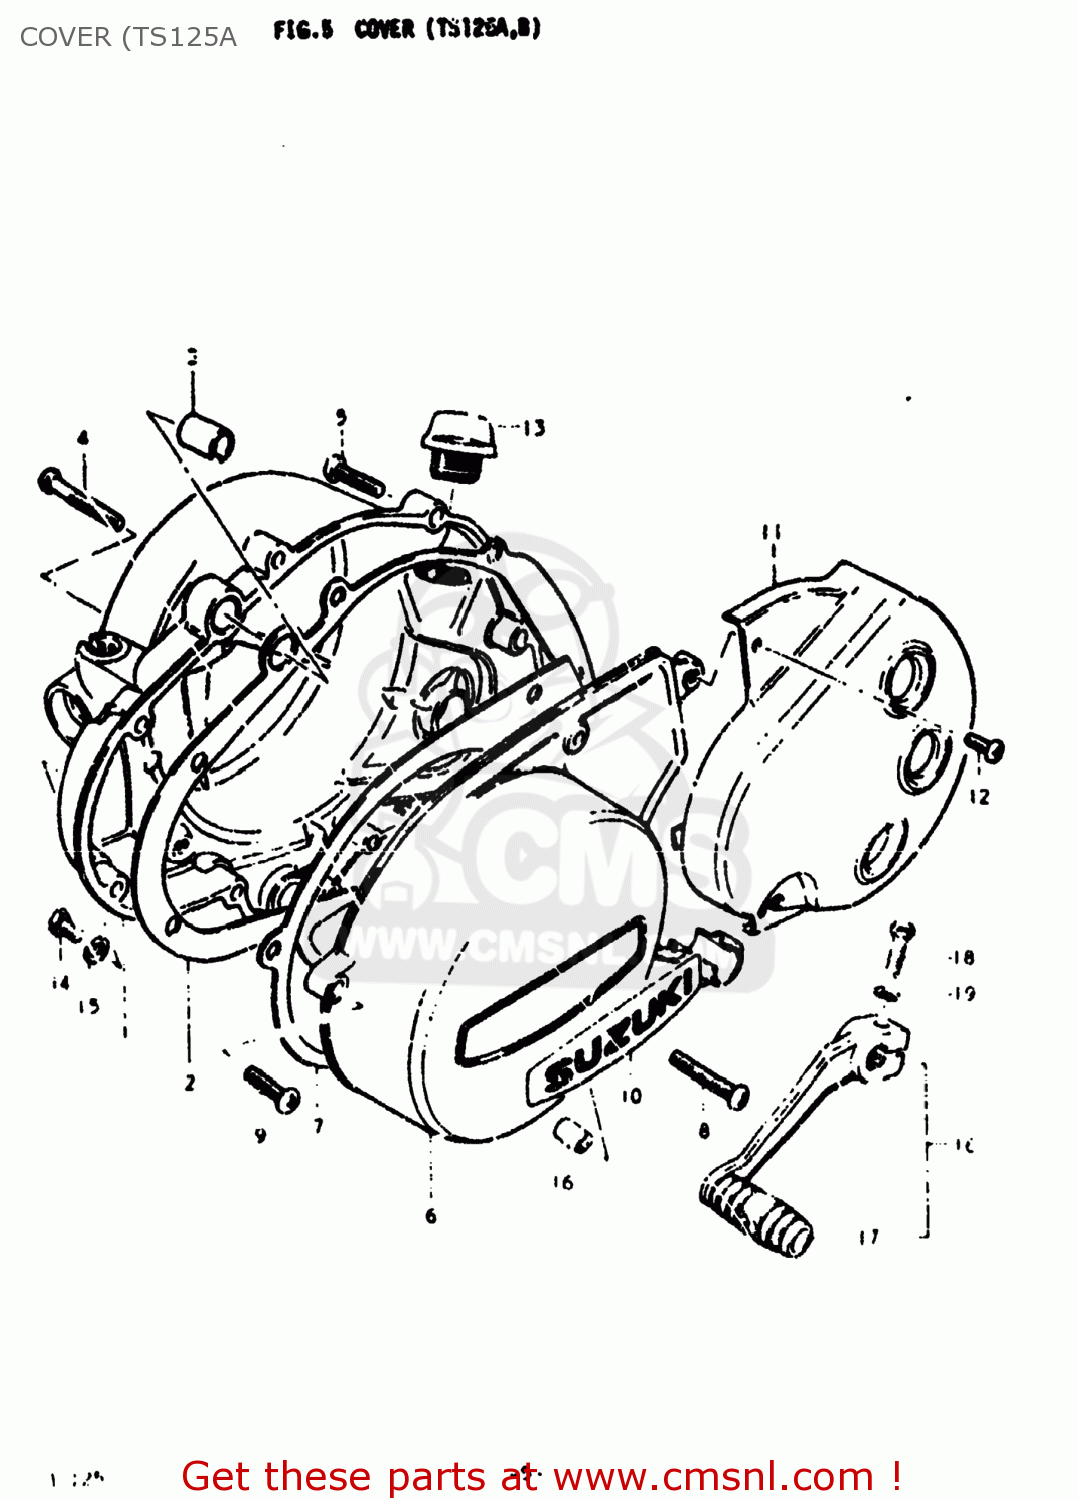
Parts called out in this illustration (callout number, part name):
1	CLUTCH COVER
2	GASKET,CLUTCH COVER (MCA)
3	PIN
4	SCREW (6X45)
5	SCREW
6	COVER
7	GASKET,CLUTCH COVER (NAS)
8	SCREW
9	SCREW
10	EMBLEM,MAGNETO COVER
11	COVER,ENGINE SPROCKET GLOSS
12	SCREW
13	PLUG,OIL FILTER
14	SCREW(6X10)
15	GASKET(6.2X11X1) (NAS)
16	LEVER ASSY,GEAR SHIFT
17	RUBBER,GEAR SHIFT PEDAL
18	BOLT
19	WASHER,LOCK
